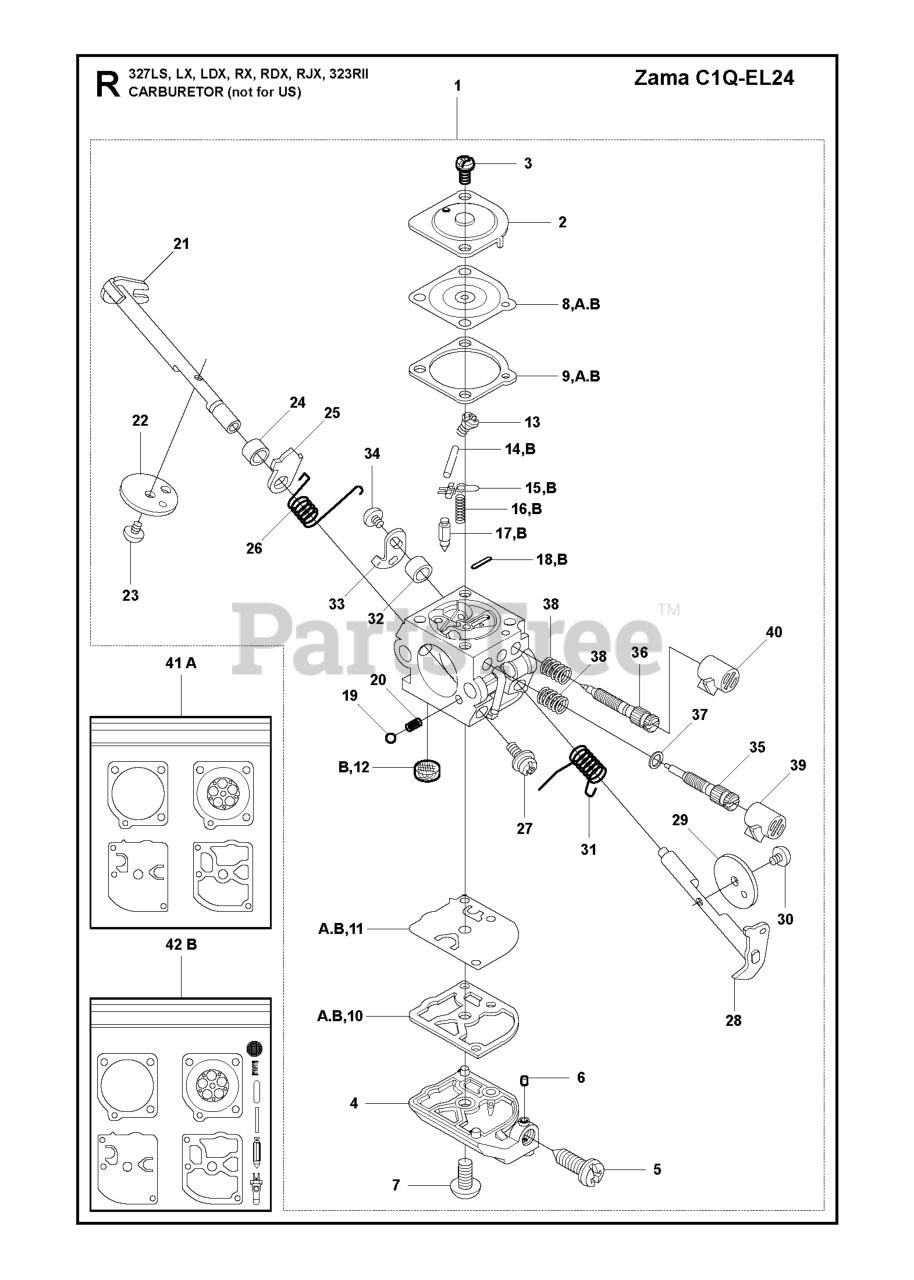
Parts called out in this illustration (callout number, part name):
1	CARBURETOR
11	PUMP DIAPHRAGM
14	PIN RETAINING SCREW
16	SPRING
17	INLET NEEDLE
21	CHOKE SHAFT
29	THROTTLE FLAP
31	SPRING THROTTLE
35	NEEDLE HIGH SPEED
36	LOW SPEED NEEDLE
38	SPRING
